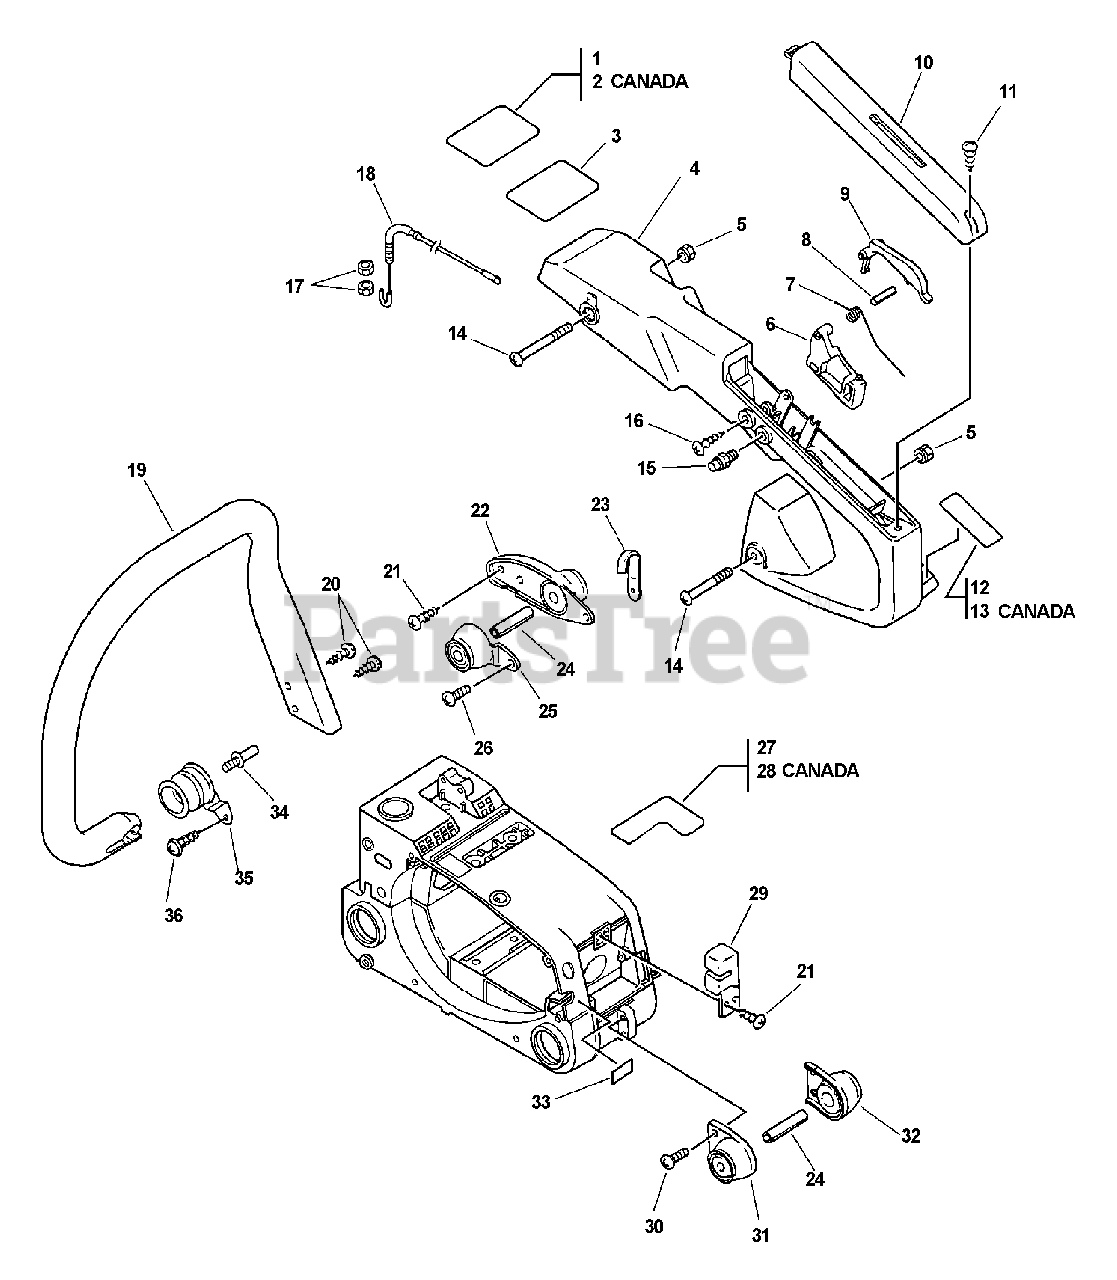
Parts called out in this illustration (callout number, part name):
1	LABEL - KICK BACK
2	LABEL - WARNING -- KICKBACK
3	LABEL - NOISE
4	HANDLE - REAR
5	NUT - 5 -- FLANGE
6	TRIGGER, THROTTLE
8	ROLLER - 4X19.8
9	LOCKOUT, THROTTLE
10	COVER, HANDLE
11	SCREW - 4X22
12	LABEL - CAUTION -- SPANISH
13	LABEL - ATTENTION
14	SCREW - 5X57
15	LATCH, THROTTLE
16	SCREW - 4X25
18	CABLE, THROTTLE
19	HANDLE - FRONT
20	SCREW - 5X20 -- TAPPING
21	SCREW - 4X14
22	CUSHION - UPPER
24	COLLAR - 6
25	CUSHION - UPPER
26	SCREW - 4X10
27	LABEL - WARNING
28	LABEL - WARNING
30	SCREW - 4X14
31	CUSHION - LOWER
32	CUSHION - LOWER
33	LABEL - STOP
36	SCREW - 4X16
